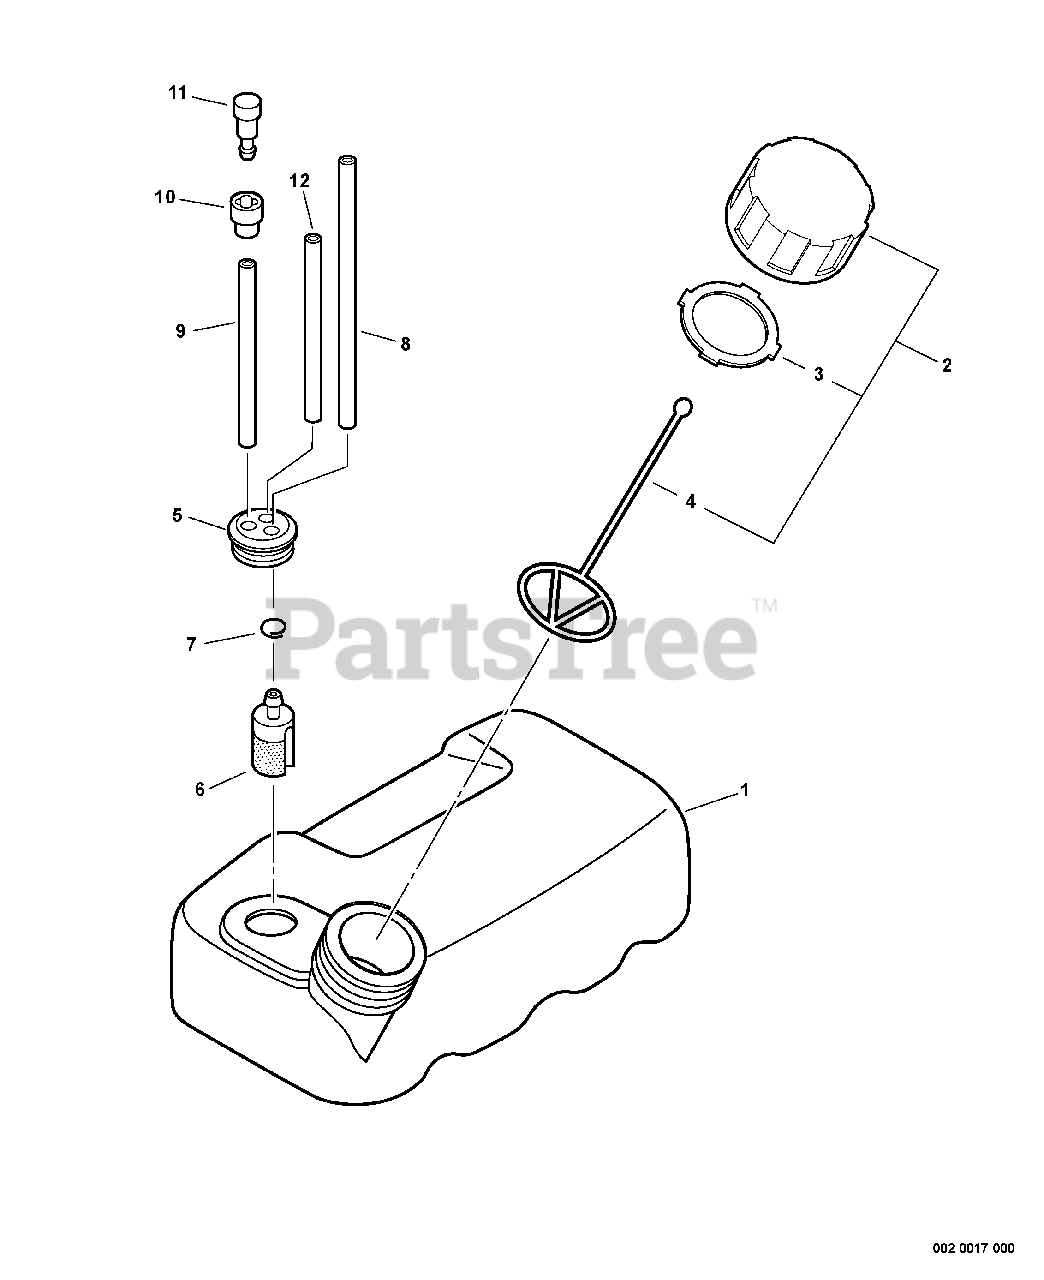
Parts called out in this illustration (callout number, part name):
1	TANK, FUEL
2	CAP ASSY, FUEL
3	GASKET, FUEL CAP
4	CONNECTOR, CAP L= 100 MM
5	GROMMET, FUEL
6	FILTER, FUEL
7	CLIP Ø6.5 MM
8	PIPE, FUEL 3×6×200
9	PIPE, FUEL 3×6×100
10	HOLDER, VENT
11	VENT ASSY
12	PIPE, FUEL 3×6×100
13	TUNE-UP KIT
14	TUNE-UP KIT
